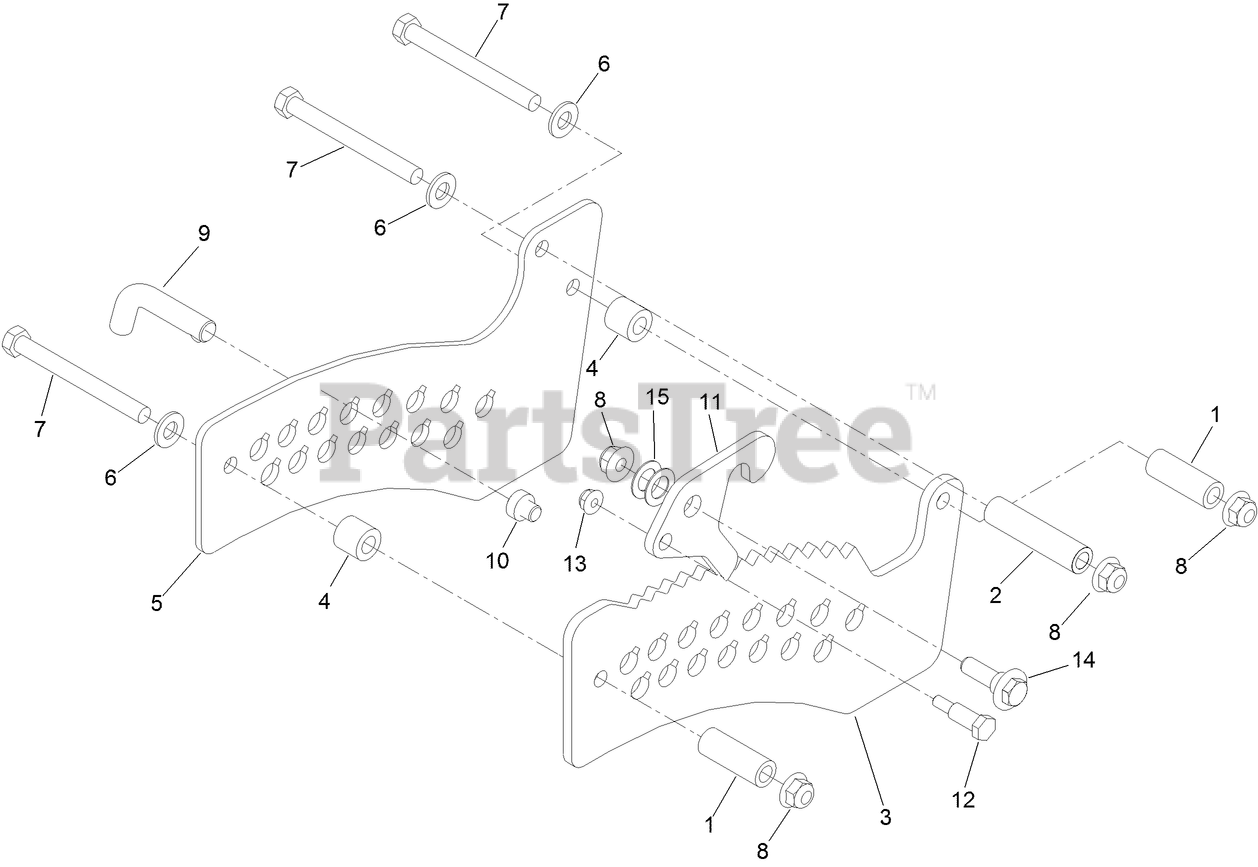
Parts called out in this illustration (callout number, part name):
1	SPACER
2	SPACER
3	PLATE-HOC, INNER
4	SPACER
5	HOC PLATE AND DECAL ASM
6	WASHER-FLAT
7	SCREW-HH
8	NUT-HF, NI
9	PIN-HOC
10	PLUG-WEAR
11	LATCH-HOC
12	BOLT-SHOULDER
13	NUT-HF
14	SCREW-SHOULDER, HWH
15	WASHER
